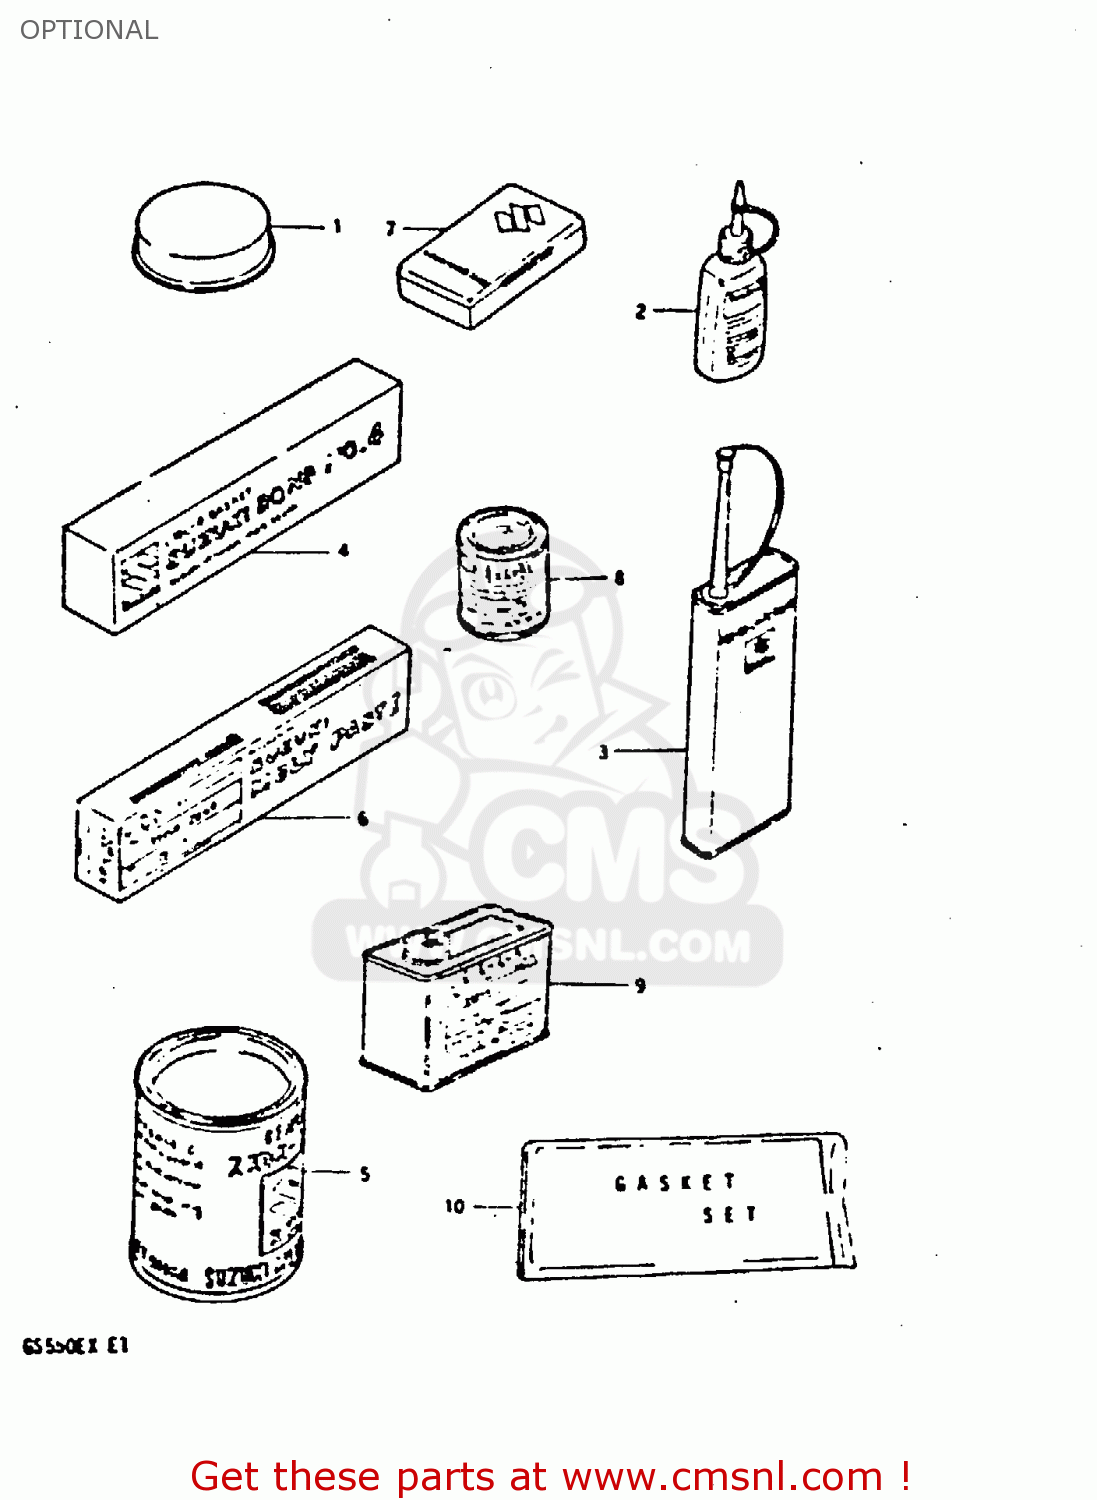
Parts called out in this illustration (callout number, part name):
1	GREASE,PBC FOR BRK PAD 20G
2	THREAD LOCK SUPER (1332B)
3	THREAD LOCK NO.1401 CLEAR 200G
4	BOND 1104
5	GREASE(C)EP2 LITHIUM 150G
6	SUZUKI MOLY PASTE
7	TUBE REPARING TOOL
8	PAINT,BLACK
9	PAINT (BLACK)
10	GASKET SET (MCA)
